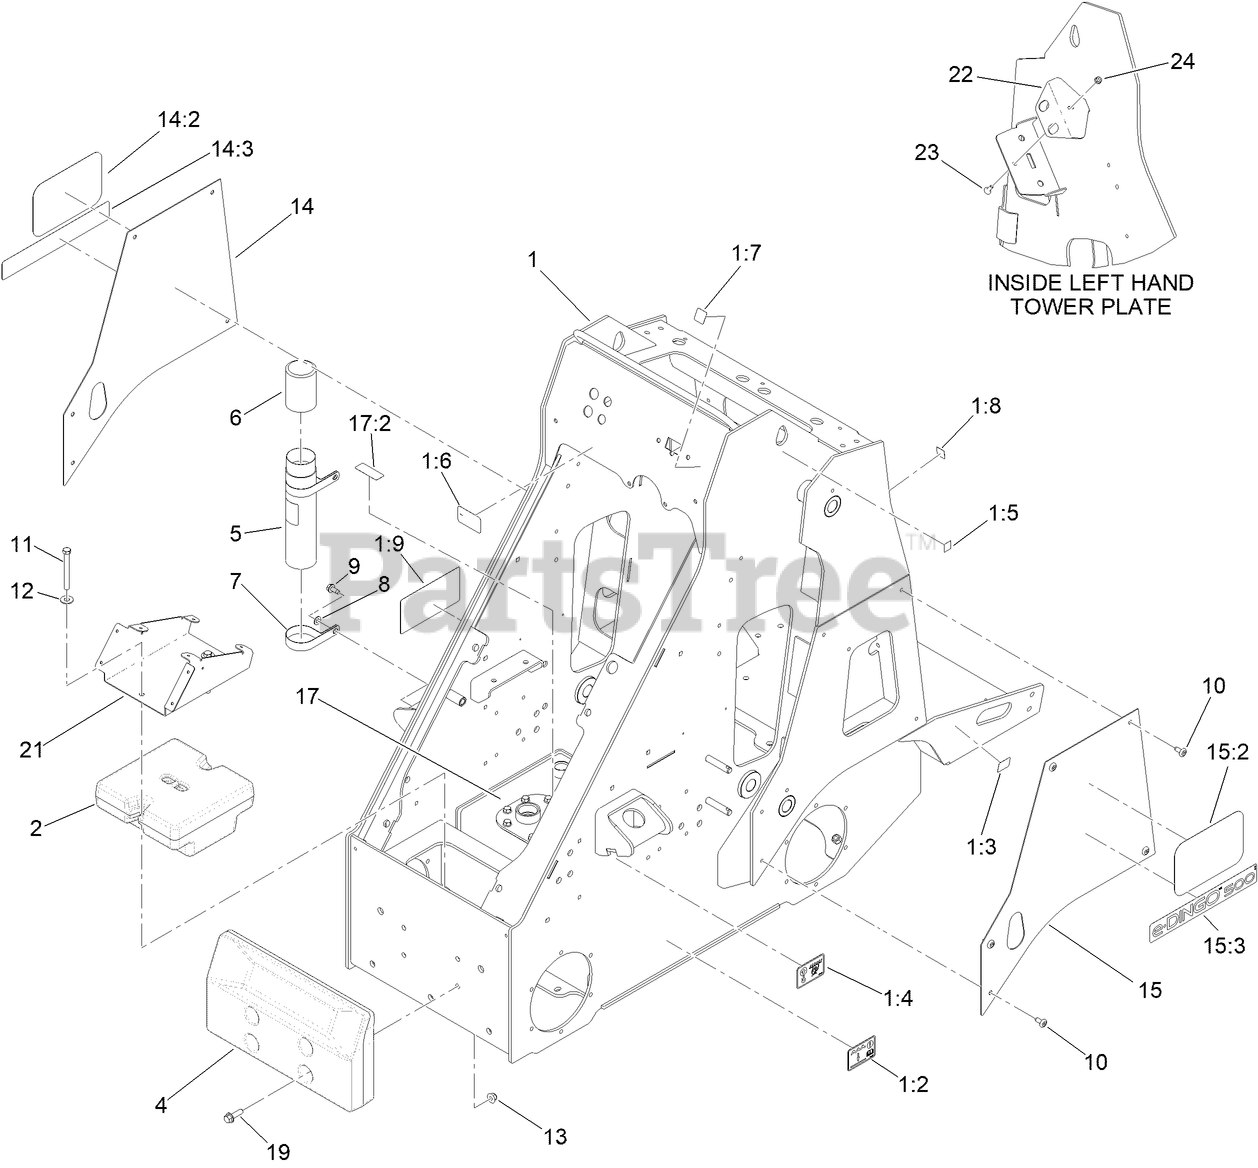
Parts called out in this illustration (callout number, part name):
1	MAIN FRAME ASM
1:2	DECAL-WATER LEVEL
1:3	DECAL-TIEDOWN
1:4	DECAL-LIFT/TIE DOWN
1:5	DECAL-POINT, LIFT
1:6	DECAL - FUSES
1:7	DECAL-LIGHT, WARNING
1:8	DECAL-GROUND, EARTH
1:9	DECAL - QUICK REFERENCE AID
2	COUNTERWEIGHT-FRONT
4	COUNTERWEIGHT-FRONT
5	TUBE-MANUAL
6	CAP-HOUSING
7	CLAMP-R
8	WASHER-PLAIN
9	SCREW-HWHTF
11	SCREW-HH
12	WASHER-FLAT
13	NUT-HF, NI
14	PANEL-ACCESS, RH
14:2	DECAL-LOGO, SILVER
14:3	DECAL- E-DINGO
15	PANEL-ACCESS, LH
15:2	DECAL-LOGO, SILVER
15:3	DECAL- E-DINGO
17	PLATE - COVER
17:2	DECAL-OIL, HYD
19	SCREW-HHF
21	BRACKET-MOUNT, FAN
22	BRACKET-FITTING, ADJUSTABLE
23	BOLT-CARR
24	NUT-FLANGE, NI
